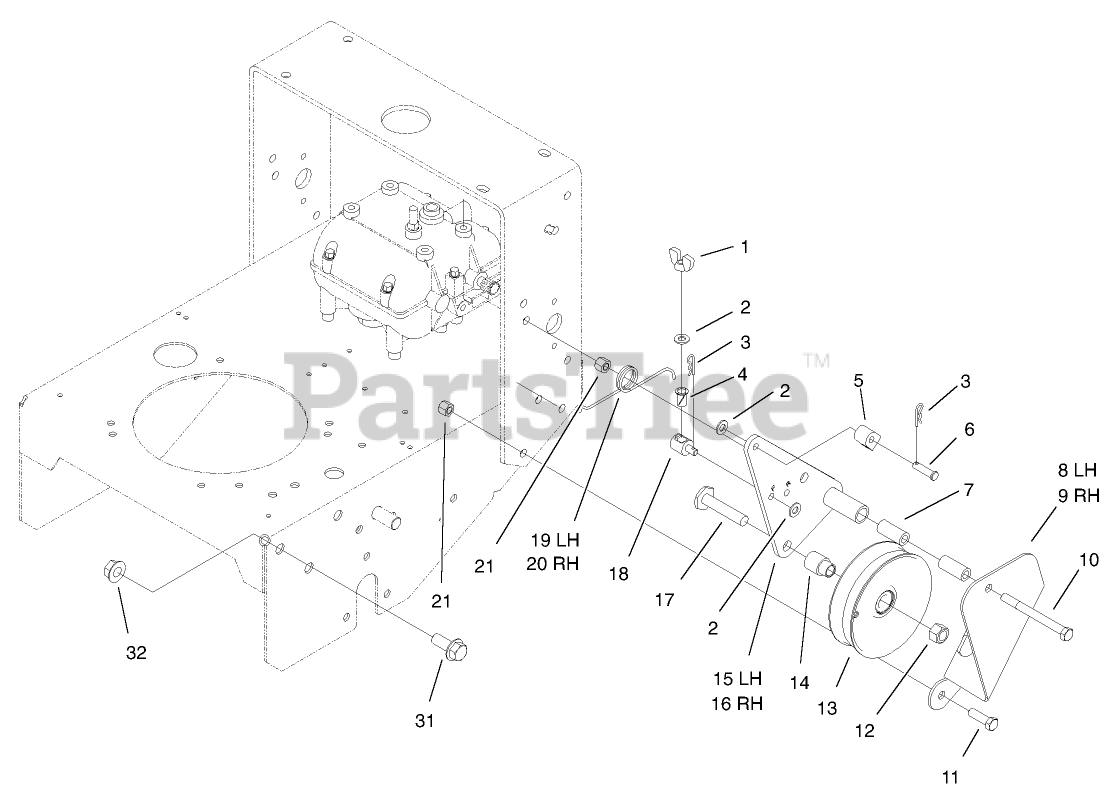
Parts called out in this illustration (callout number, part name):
1	NUT-WING
2	WASHER-PLAIN
3	PIN-COTTER
4	BUSHING-NYLON
5	FITTING-ROD
6	PIN-CLEVIS
7	SPACER-PIVOT, IDLER
8	BRACKET-SUPPORT, LH
9	BRACKET-SUPPORT, RH
10	SCREW-HH
11	SCREW-HH
12	NUT-LOCK, NI
13	PULLEY-IDLER
14	SPACER-PULLEY
15	BRACKET-IDLER, LH
16	BRACKET-IDLER, RH
17	SCREW-LEVELER
18	FITTING-ROD
19	SPRING-TORSION, LH
20	SPRING-TORSION, RH
21	NUT-LOCK, NI
31	SCREW-HHF
32	NUT-HF
